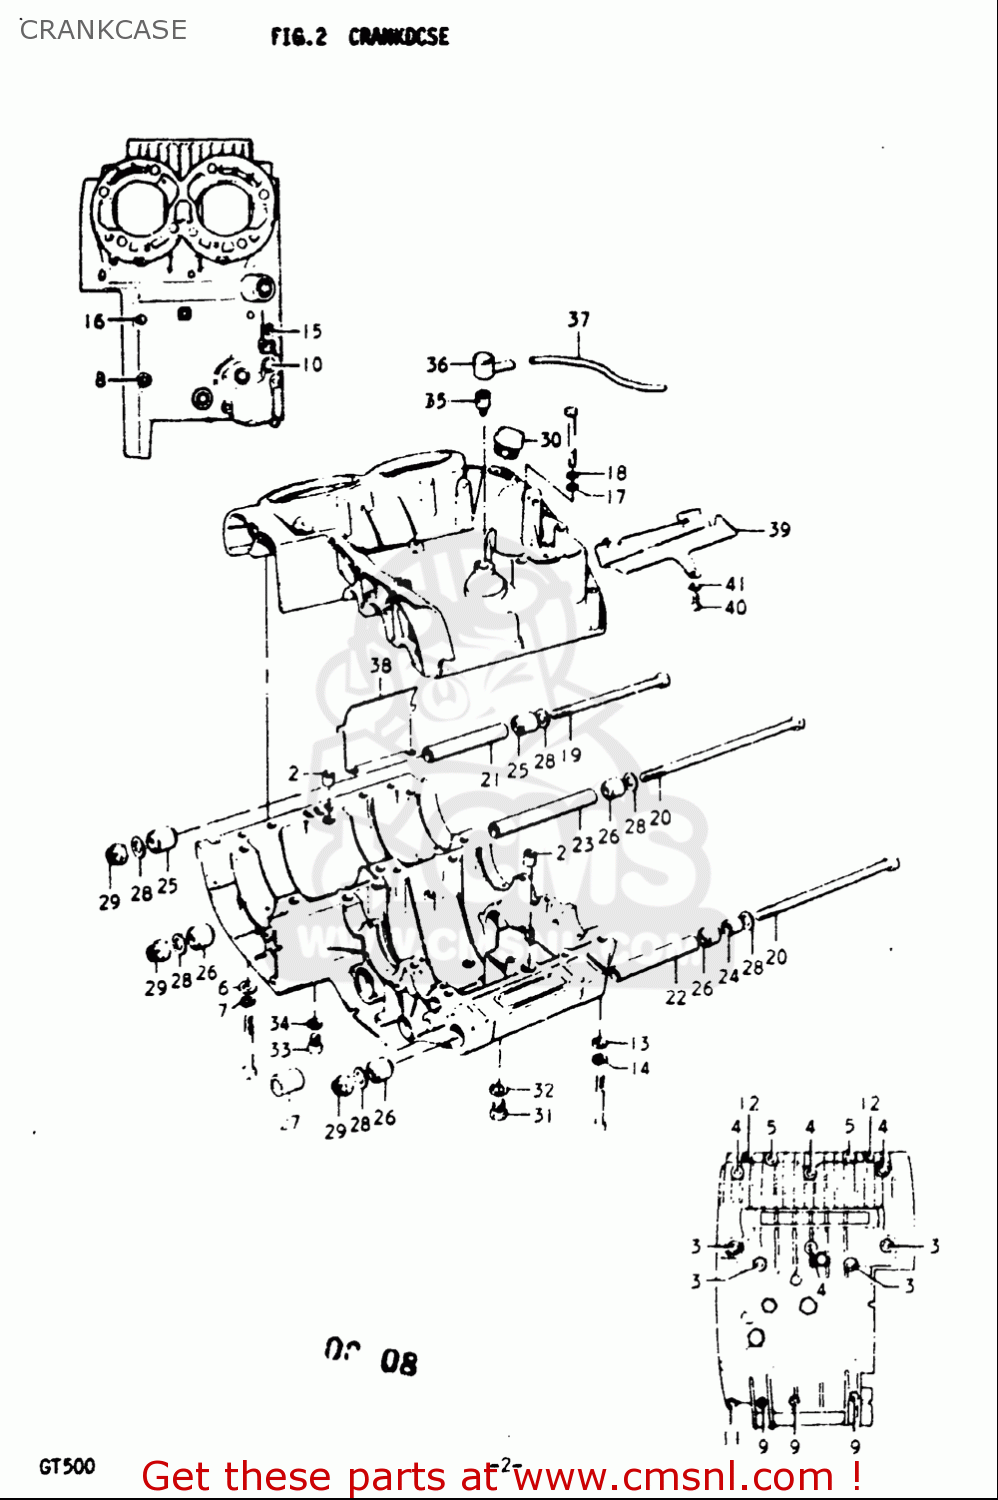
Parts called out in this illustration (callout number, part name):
2	PIN
4	BOLT
5	BOLT
6	WASHER
7	WASHER,LOCK
8	BOLT
9	BOLT
10	BOLT
11	BOLT
12	BOLT
13	WASHER
14	WASHER,LOCK
15	BOLT 6X95 HEXAG
16	BOLT(6X70)
17	WASHER
18	WASHER,LOCK
25	BUSHING
